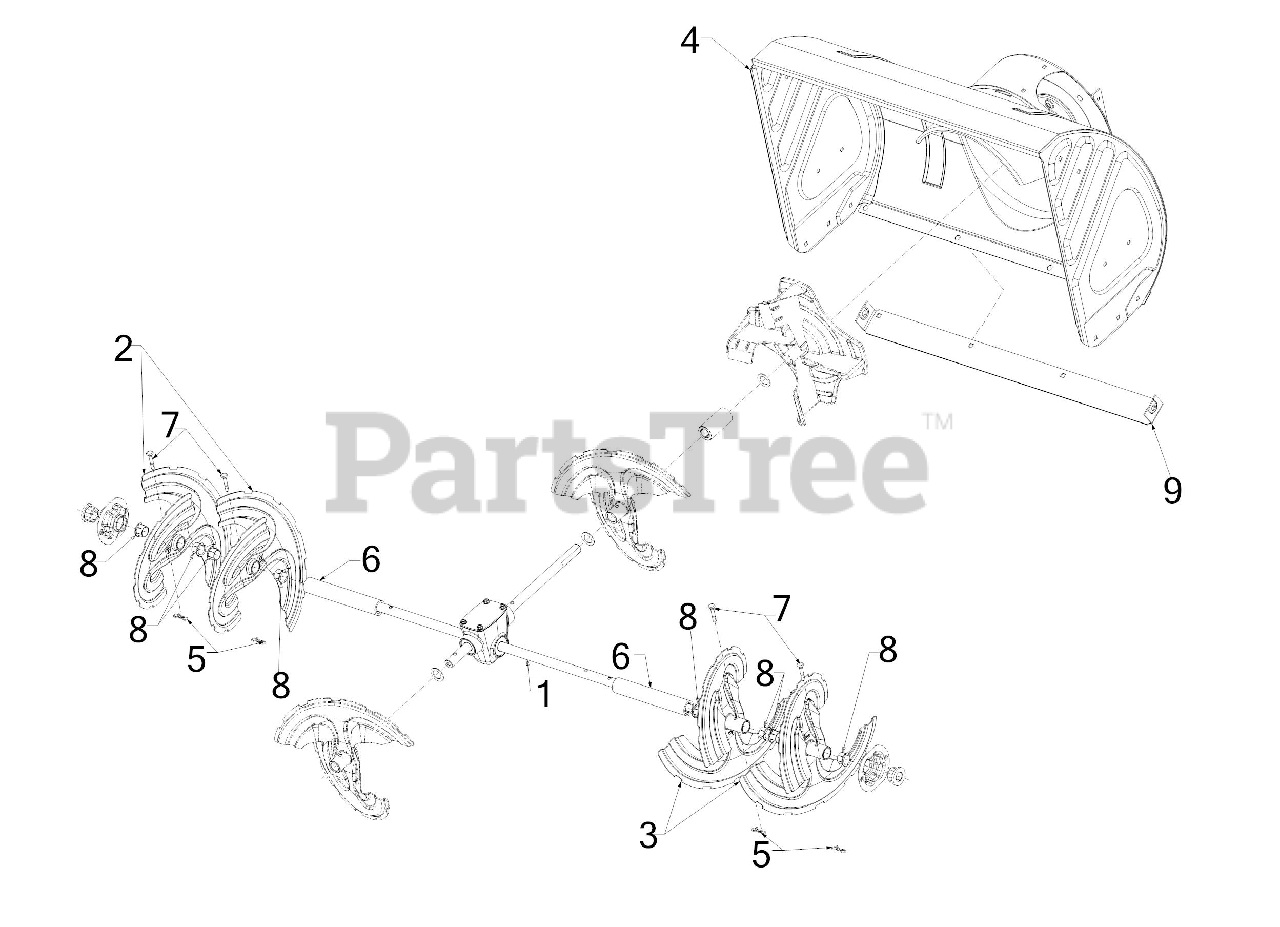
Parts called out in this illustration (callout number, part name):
1	30" AUGER GEARBOX ASSEMBLY
2	SPIRAL ASSEMBLY (RH)
3	SPIRAL ASSEMBLY (LH)
4	30" AUGER HOUSING
5	BOW TIE COTTER PIN 1/4-5/16
7	SHEAR PIN .25 x 1.50 GR2
8	FLANGE BUSHING
9	30" SHAVE PLATE
